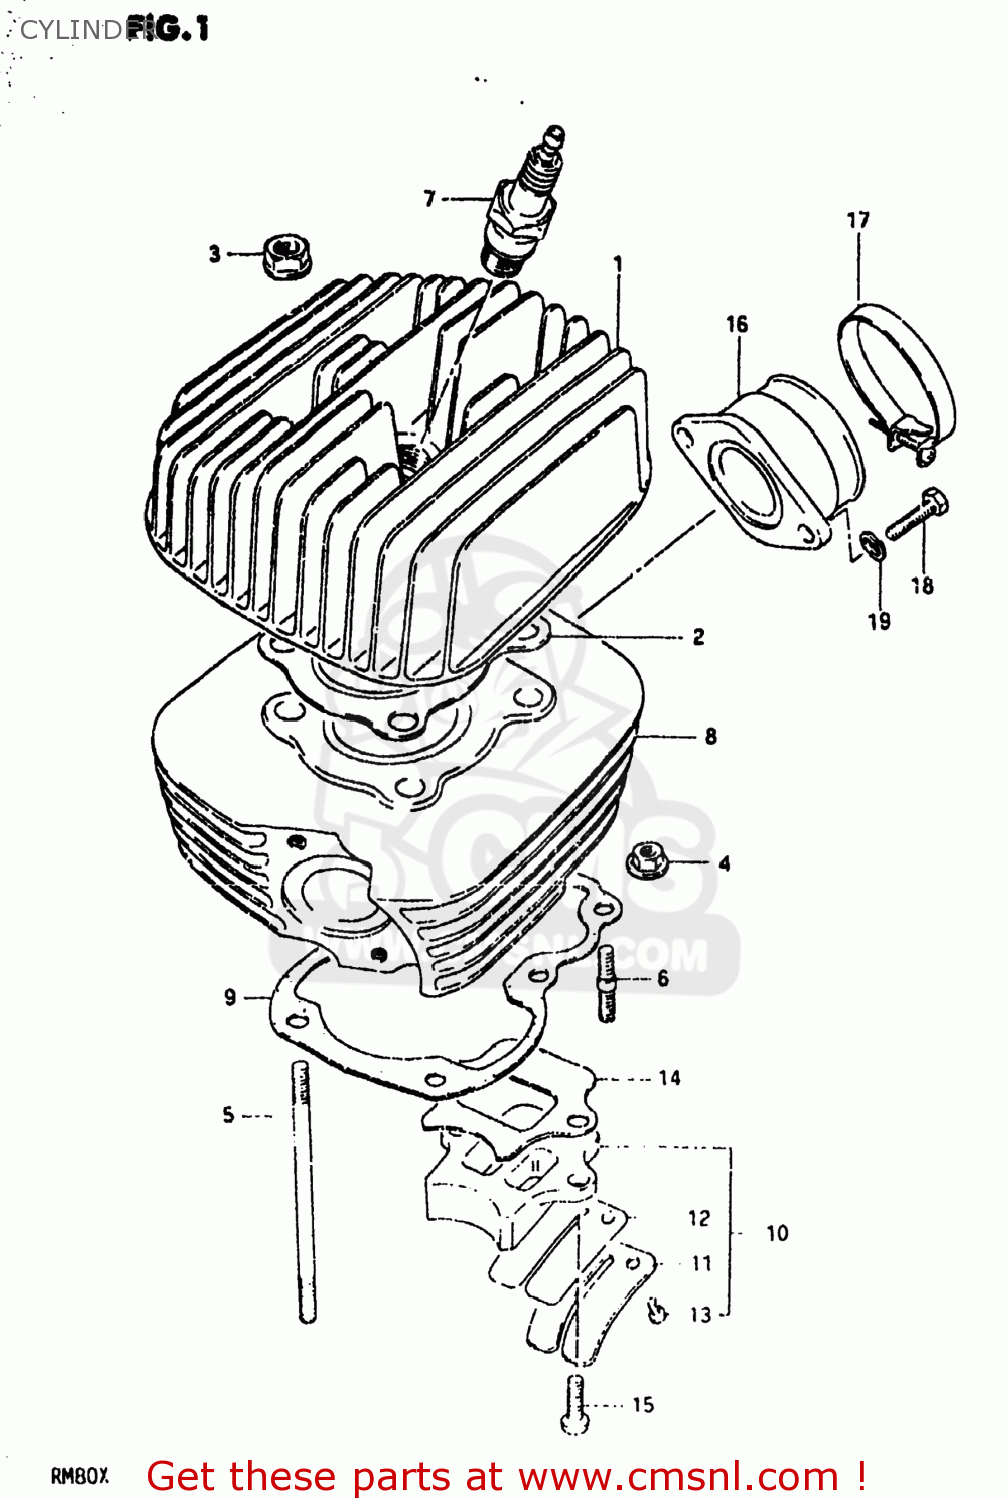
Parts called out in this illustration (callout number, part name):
1	HEAD,CYLINDER
2	GASKET,CYLINDER HEAD (NAS)
3	NUT
4	NUT
5	BOLT,STUD
6	STUD 6X20
7	PLUG,SPARK
8	CYLINDER
9	GASKET,CYLINDER (MCA)
10	VALVE ASSY,REED
11	STOPPER,REED VALVE
12	VALVE,REED
13	SCREW,REED VALVE
14	GASKET,REED VALVE (MCA)
15	SCREW
16	PIPE,INTAKE
17	CLAMP
18	BOLT
19	LOCK WASHER
